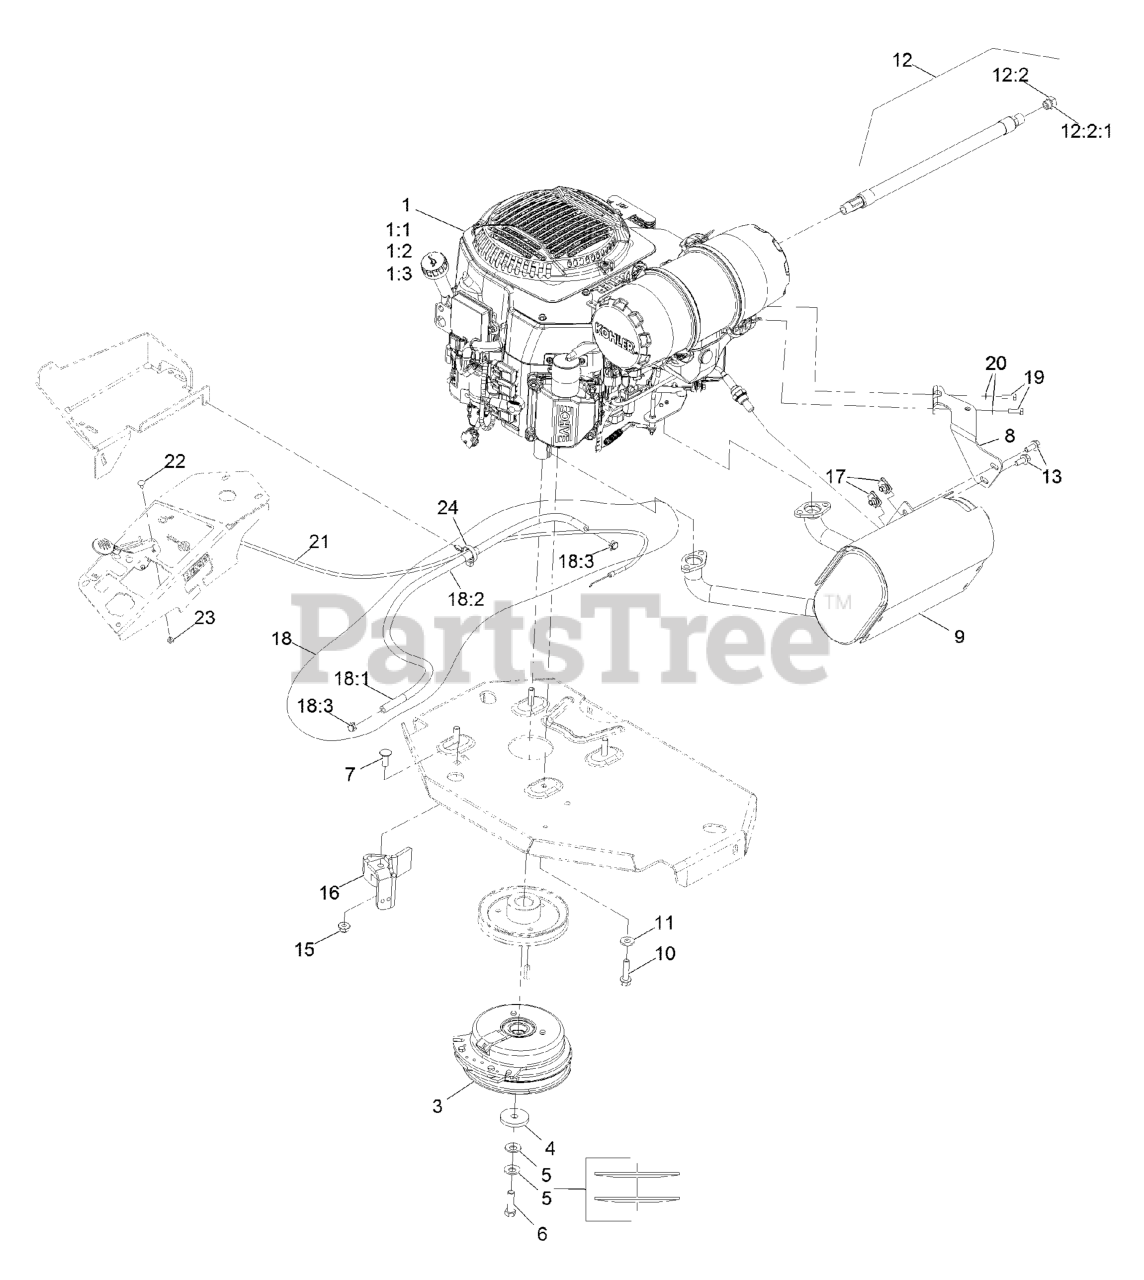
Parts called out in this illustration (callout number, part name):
1:1	Kohler 52 050 02-S Engine Oil Filter
1:2	Kohler 25 083 01-S Engine Air Filter
1:3	Kohler 25 083 04-S Safety Filter
3	CLUTCH KIT
4	WASHER-CLUTCH
5	WASHER-SPRING
6	SCREW-HH 7/16-20 X 1 1/2 W/LOCTITE
7	SCREW-CARR
8	MUFFLER BRACKET KIT
10	SCREW-HWH
11	WASHER-BELLEVILLE
12	OIL DRAIN HOSE ASM
12:2	PLUG-HH
12:2:1	O-RING
13	SCREW-HHF
15	NUT-HF, NI
16	CLUTCH-ANCHOR
18	FUEL LINE ASM
18:1	HOSE-FUEL
18:2	SLEEVE-THERMAL
18:3	CLAMP-HOSE
19	SCREW-HH M6-1 X 20Mm W/Patch
20	WASHER-SPRING
